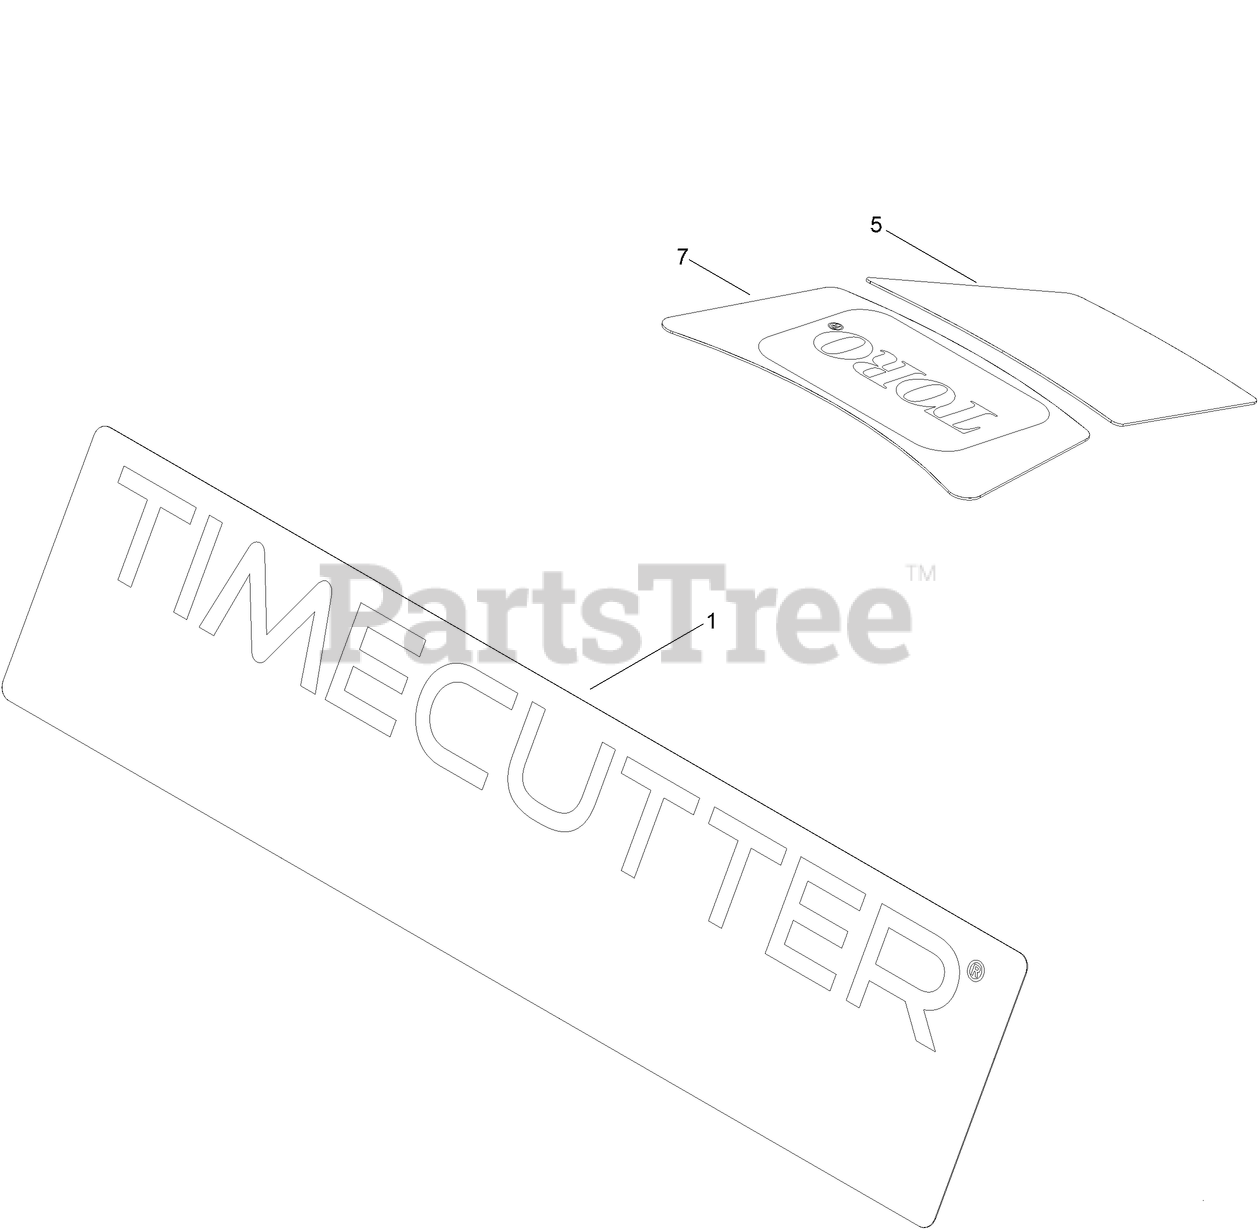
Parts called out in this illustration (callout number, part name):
1	DECAL-TIMECUTTER
5	DECAL-DISPLACEMENT, ENGINE
7	DECAL-ENGINE
